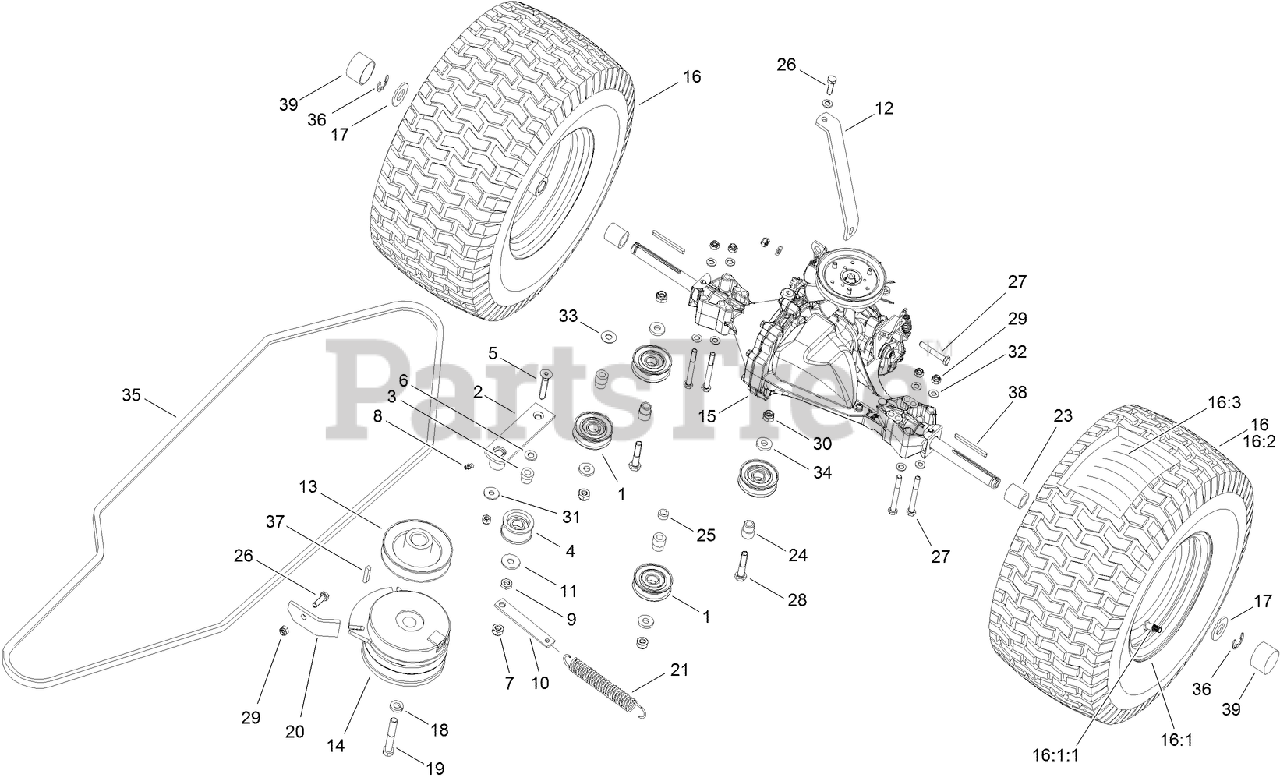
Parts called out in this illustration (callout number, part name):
1	PULLEY-IDLER
2	ARM-IDLER
3	BUSHING-IDLER
4	PULLEY-IDLER
6	WASHER-FLAT
7	NUT-LOCK
8	FITTING-GREASE
9	NUT-HEX
10	BRACKET-TENTION
11	WASHER
12	BRACKET
13	PULLEY-ENGINE
14	CLUTCH-ELECTRIC
15	TRANSMISSION ASM
16	Loose Parts Package
16:1	RIM-REAR
16:1:1	Valve-Tire
17	WASHER
18	WASHER-SPRING, BELLEVILLE
19	SCREW-HH
20	BRACKET-RETAINER
21	SPRING
23	SPACER-AXLE
24	BUSHING
26	SCREW-HH
27	CAPSCREW
28	SCREW-HH
29	NUT-LOCK, NI
30	NUT-LOCK
31	WASHER-PLAIN
32	WASHER-PLAIN
33	Washer
34	WASHER-FLAT
35	V-BELT, TRACTION
36	CLIP-SPRING
37	KEY-SQUARE
38	KEY-SQUARE
39	CAP-HUB
